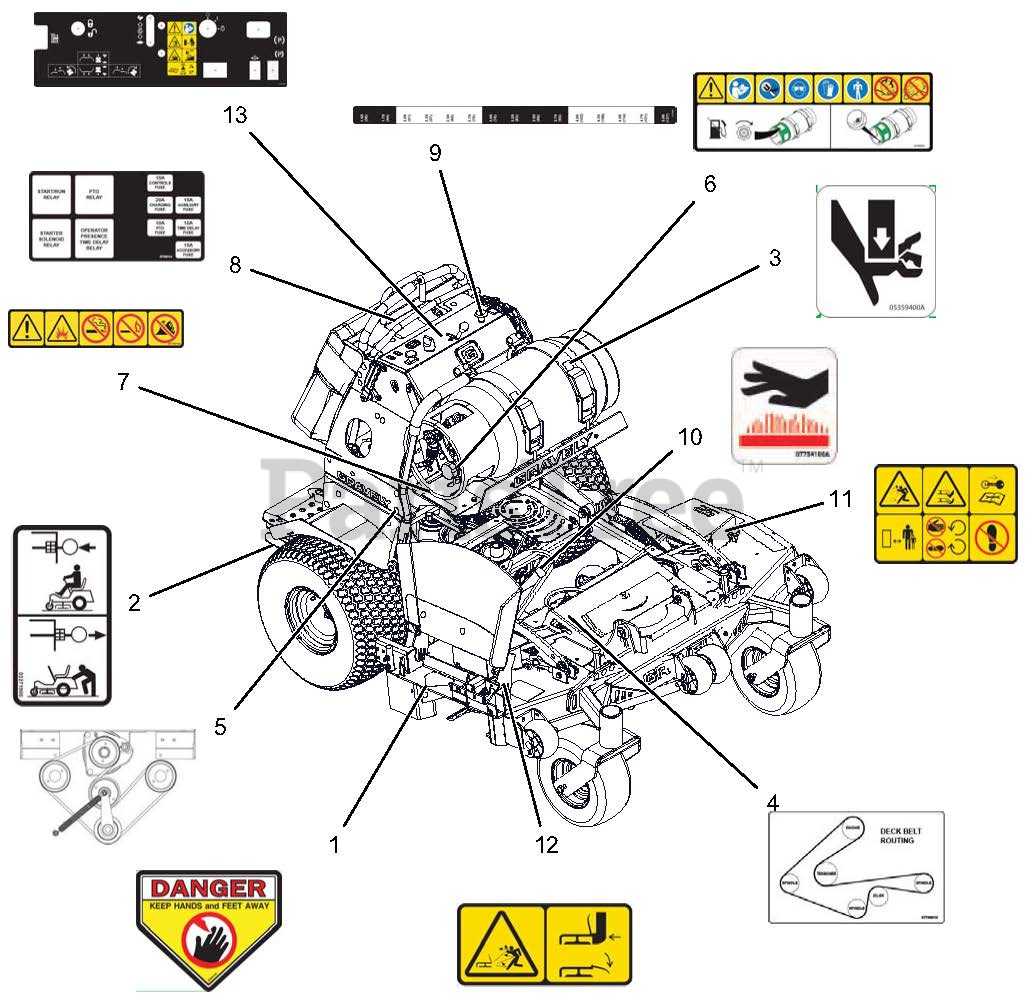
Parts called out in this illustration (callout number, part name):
1	DECAL, DANGER
2	DECAL, TRANSMISSION DISCONNECT
3	DECAL, PINCH POINT
4	DECAL, BELT ROUTING 48/52
5	DECAL, PROSTANCE HYD BELT ROUT
6	DECAL, HORZ.MOWER TANKS ONLY
7	DECAL, LP SAFETY
8	DECAL, FUSE BLOCK
9	DECAL, 48-60 PS HOC DIAL
10	DECAL, HOT SURFACE
11	DECAL, SAFETY - MOWER DECK
12	DECAL, SAFETY - DECK GUARDING
13	DECAL, PS CONTROL PANEL EFI
